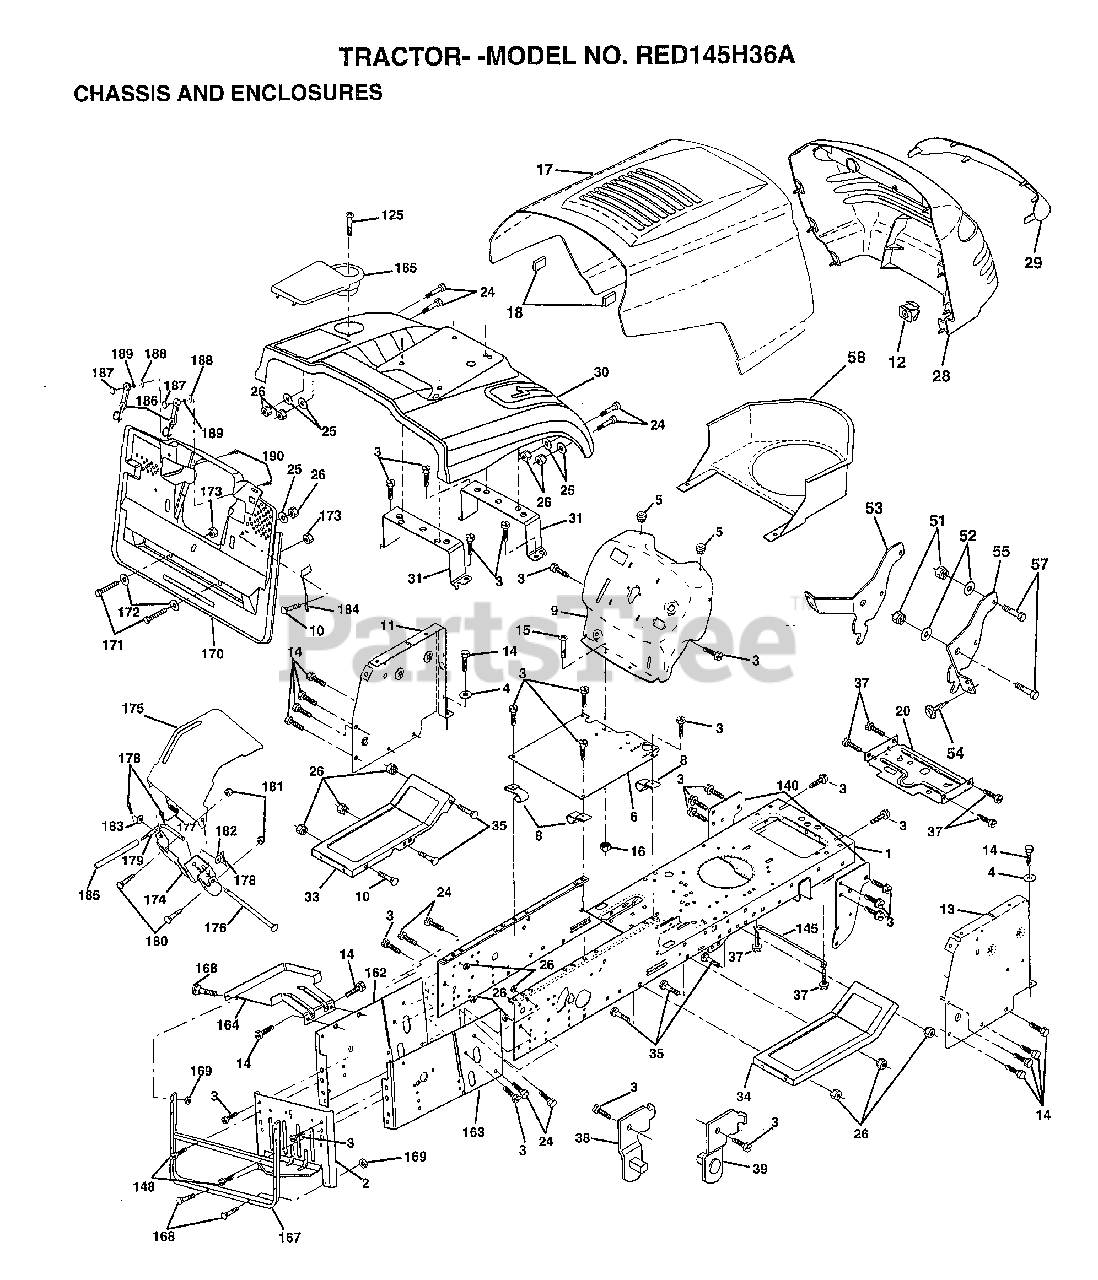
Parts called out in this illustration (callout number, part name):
1	CHASSIS.STAMPING
2	DRAWBAR.CRD
3	SCREW
4	WASHER
5	BUMPER-HOOD/DASH
6	SADDLE
8	"CLIP,INSULATOR"
9	DASH.SILKSCREEN
11	"PANEL-DASH,LH"
12	CLIP.TINNERMAN
14	SCREW LT
15	SCREW
17	HOOD.STEEL.ASSY
20	"PLATE-MTG,BATT/FU"
24	BOLT
25	WASHER
26	NUT
28	GRILLE WITH CLIPS
29	LENS.GRILLE
31	BRKT.SUPT.FENDER.CRD
33	FOOTREST LH
34	FOOTREST RH
35	BOLT
37	SCREW LT
38	BRACKET ASM LH
39	BRACKET ASM RH
51	NUT
52	WASHER
53	BRACKET.GRILLE.LH
54	SCREW.HEX.WS.HD
55	BRACKET.GRILLE.RH
58	AIR DUCT
68	NUT
125	SCREW
129	WASHER
134	ROD SUPPORT HOOD
140	BRKT SUSPENSION
145	"ROD POVOT,CHASSIS"
148	SCREW
162	BRKT.EXT.CHASSIS.LH.CRD
163	BRKT.EXT.CHASSIS.RH.CRD
164	SUPPORT.BATTERY.CRD
165	COVER.BATTERY.CRD.BLACK.LT
166	"SCREW,HWHD.HI-LO#13-16X3/4"
167	SUPT.ASM.BACKPLATE
168	BOLT-RD HD SQ NK
170	COVER.BACKPLATE.BLACK
171	BOLT
173	NUT
174	BRKT.SWITCH.FBI.CRD
175	GRUARD.DOOR.REAR.CRD
176	HINGE PIN
177	SPRING.COVER.LH
179	ROD.PIVOT.FBI.CRD
182	WASHER.385X.625
183	WASHER
184	BRKT.ACTUATOR.BAG.CRD
185	TUBE.LEVER.SWCH.FBI.CRD
186	LATCH ASSY.BAGGER
187	WELDNUT
188	WASHER #10
189	LOCKWASHER
190	SCREW
